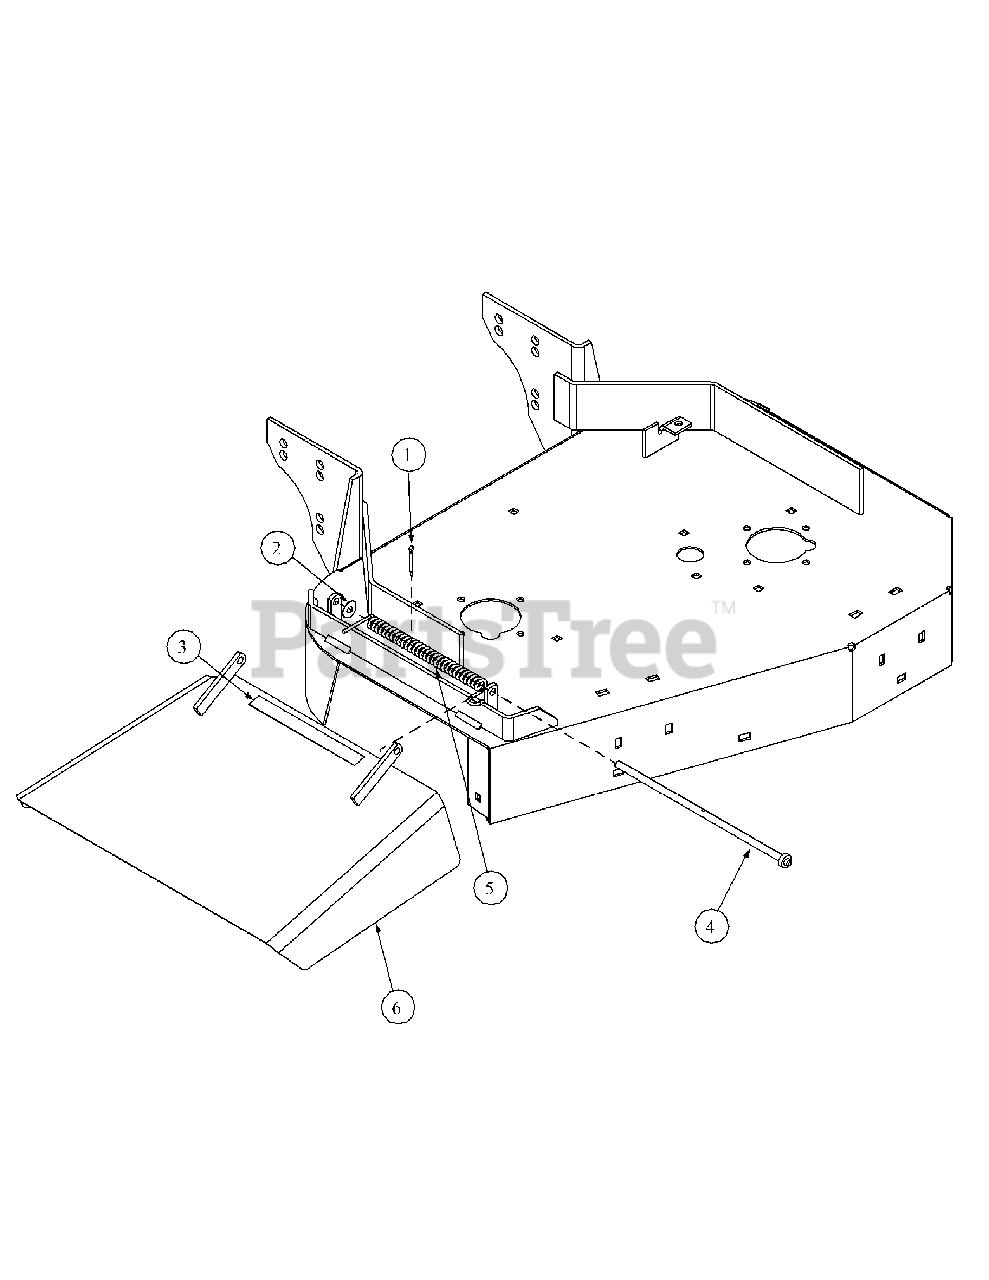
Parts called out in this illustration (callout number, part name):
1	Cotter Pin, 5/32 x 1 1/2 Zinc
2	Flat Washer, 3/8, Zinc
3	Decal, Cut Line
4	Pin, Deflector Assembly, Weldment1
5	Torsion Spring
6	Chute Assembly Discharge
